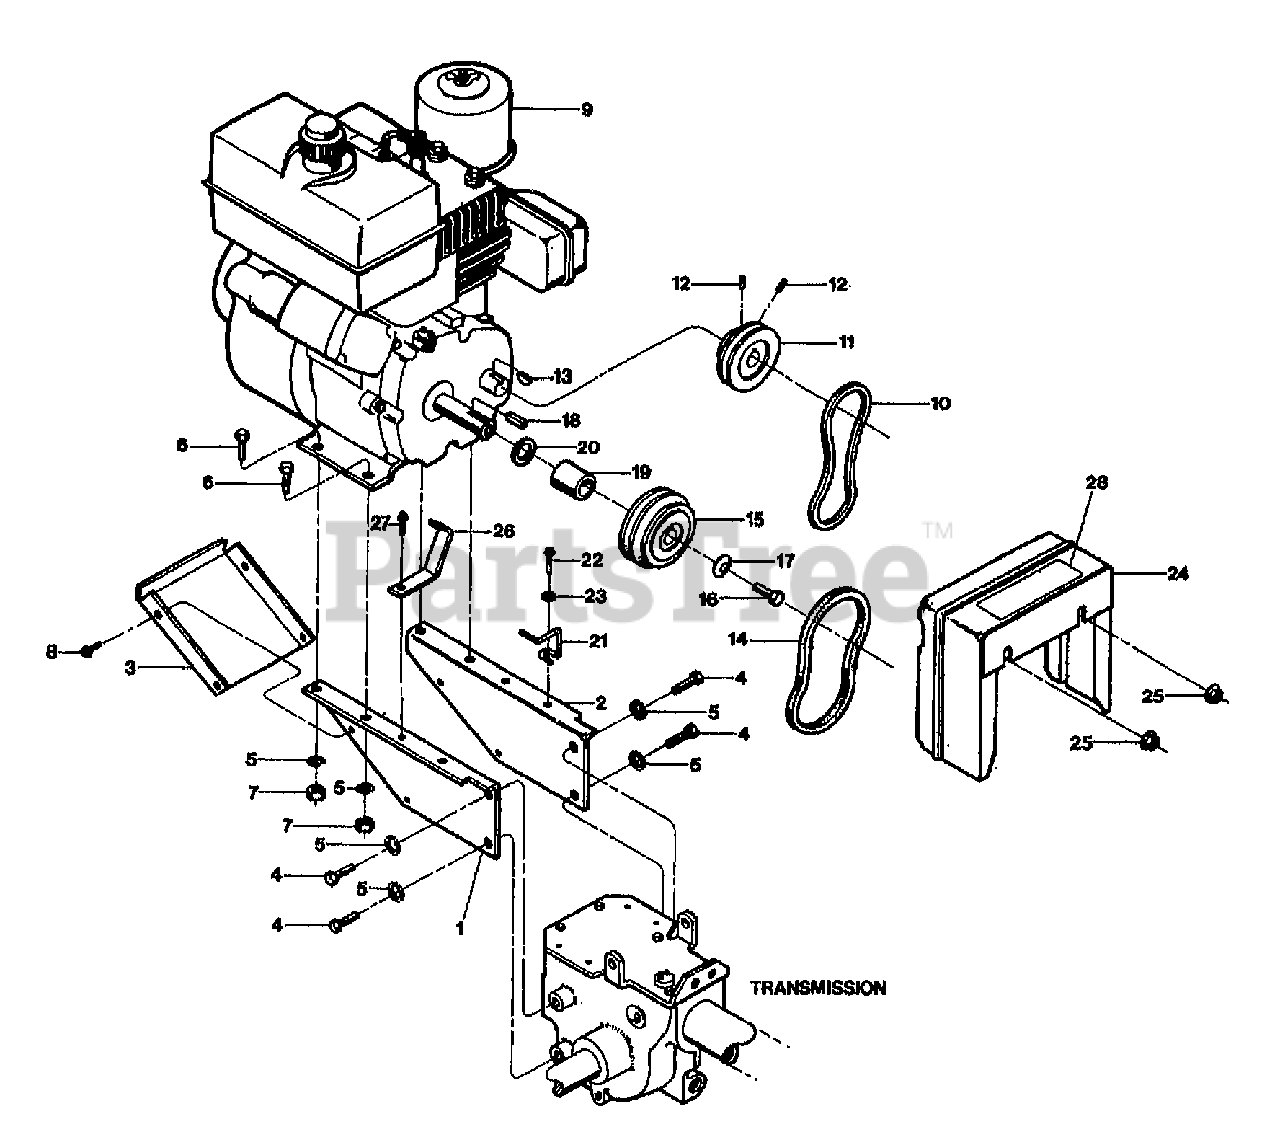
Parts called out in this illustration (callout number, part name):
1	BRKT-ENG LT P4
2	BRKT-ENG RT PNT
3	PAN-ENG BRKT PNT
4	SCR-HFLK 5/16-18X.75 GR 5 ZP
5	WASHER-LK .312 ZP
6	SCR-HHC 5/16-18X.75 GR 5 ZP
7	NUT-HEX 5/16-18 ZP
8	SCR-HH SEMS 10-32 X .5 ZP (W/PERMANENT WASHER)
9	ENGINE, TECUMSEH, 6HP RECOIL START,
10	BELT-V REV DR ECONO (SEE V-BELT SET BELOW)
11	PULLEY-REV MACH
12	SCR-SS 1/4-20 X .25 (SECURES REVERSE ENGINE PULLEY)
13	KEY-WOODRUFF #5
14	BELT-V GROOVE FWD SMFRAME
15	PULLEY-ENGINE MACH
16	SCR-HH 3/8-24X1.0 G5 ZP (SECURES FORWARD ENGINE PULLEY)
17	WASHER-.994X.413X.145
18	KEY-.188 SQX1.0
19	SPACER-.937X.755X.938
20	SHIM-1.0X.7656X.031
21	GUIDE-BELT FWD
22	SCR-HWH 1/4-20 X .75 STH
23	WASHER-FLAT 1/4 SAE
24	SHROUD-BELT W/DECAL
25	NUT-HFLK 5/16-18 ZP (WHIZ-STYLE)
26	GUIDE-BELT REV PNT
27	SCR-HWH 1/4-20 X .5 STH
28	DECAL-BELT CHG ECONO
